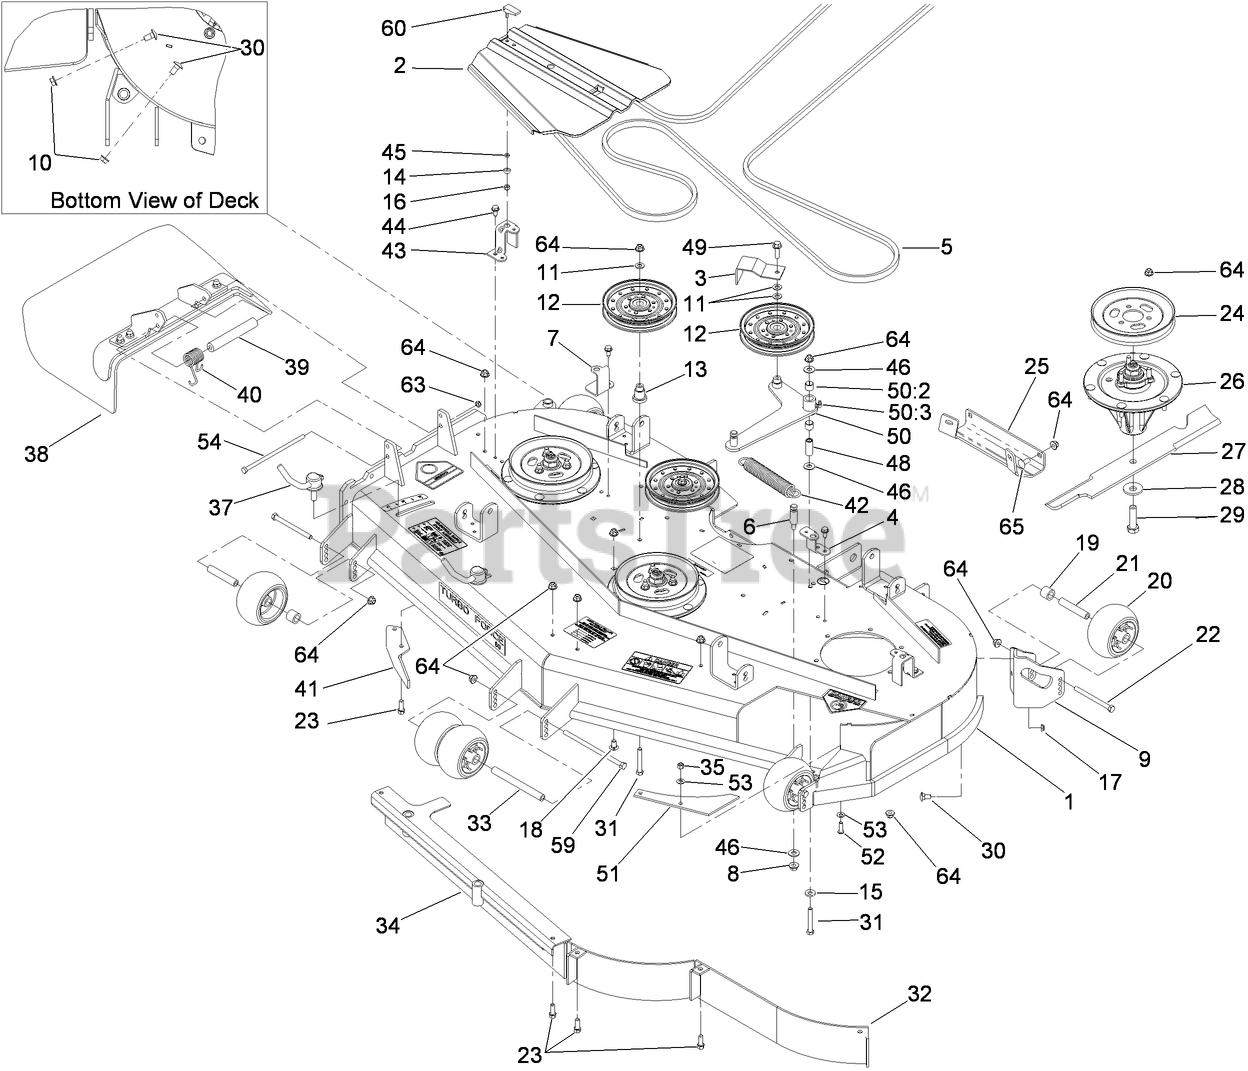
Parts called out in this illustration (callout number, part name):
1	DECK DECAL ASM
2	COVER-BELT
3	GUIDE-BELT
4	BRACKET-COVER, TALL
5	BELT-V
6	PIN-THREADED, SPRING ANCHOR
7	BRACKET-COVER
8	NUT-HF
9	MOUNT-WHEEL, LH
10	NUT-HHF, WHIZ
11	WASHER-FLAT
12	Idler-Flat
13	MOUNT-PULLEY
14	BUSHING-LATCH, SWELL
15	WASHER-BELLEVILLE
16	NUT-LOCK, HH
17	NUT-LOCK, NI
18	SCREW-CARR
19	TUBE-SPACER
20	ROLLER-SCALP, ANTI
21	TUBE-SPANNER
22	SCREW-HH
23	SCREW-HWH
24	Pulley
25	Plate-Skid
26	SPINDLE ASM
27	BLADE-HI FLOW
28	Washer-Blade Bolt, Heavy
29	SCREW-BLADE
30	SCREW-CARR
31	SCREW-HH
33	SPACER-WHEEL
35	NUT-LOCK, NI
37	LEVER ASM
38	RUBBER DEFLECTOR ASM
39	SPACER
40	SPRING-TORSION
41	BAFFLE-DISCHARGE
42	SPRING-EXTENSION
43	BRACKET-COVER
44	SCREW-HWHTF
45	WASHER
46	WASHER-FLAT
48	BUSHING
49	SCREW-HHF
50	DECK IDLER ARM ASM
50:2	SLEEVE-BEARING
50:3	FITTING-GREASE, 90 DEG
51	PLATE-TURBO
52	SCREW-HSBH
53	WASHER-SPRING
54	SCREW-HH
59	SCREW-HH
60	HANDLE-LATCH, SWELL
63	NUT-LOCK, NI
64	NUT-HF, NI
65	SCREW-CARR
